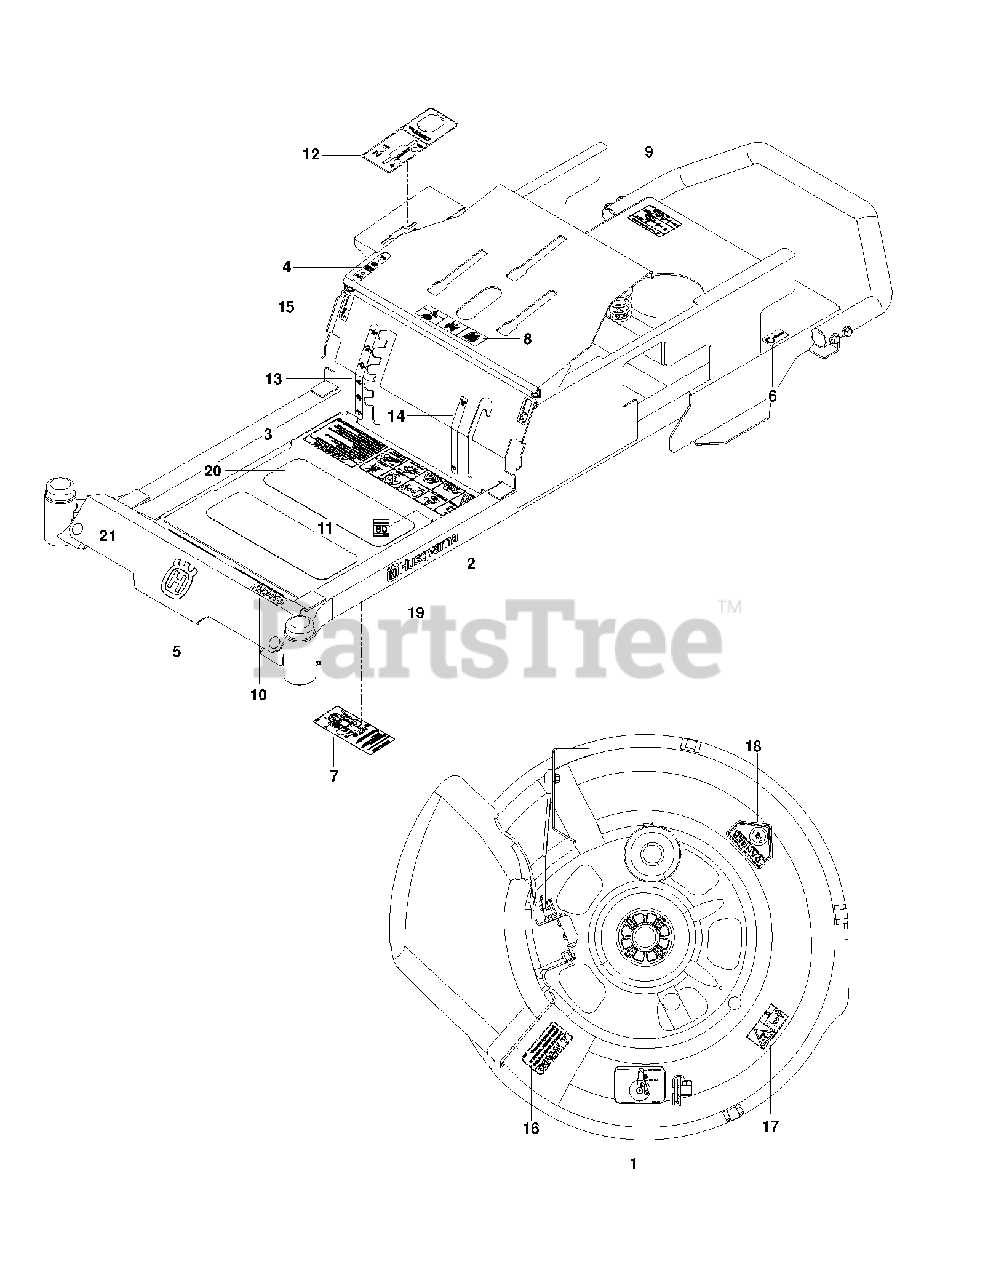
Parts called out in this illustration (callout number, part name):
1	DECAL, BELT ROUTING
2	DECAL, SAFETY WARNING
3	DECAL, WARNING
4	DECAL, PARK BRAKE
5	DECAL.AUGER.HUSQ.CROWN.SNOW
6	DECAL, ECM, AUSTRALIA
7	DECAL, SERVICE
8	EURO DECAL-BATTERY WARNIN6
9	DECAL, DO NOT TOW
10	DECAL.RZ3019
11	DECAL 80 DBA
12	DECAL, CONTROL PANEL HUS
13	DECAL, DECK HEIGHT
14	DECAL, BLADE ENGAGEMENT
15	DECAL, MOTION CONTROL
16	DECAL, CAUTION
17	DECAL, EURO SEVERING
18	DECAL, CPSC
19	RP.DECAL.BADGE.170MM.TEXTLOGO
20	ANTI-SKID PAD
